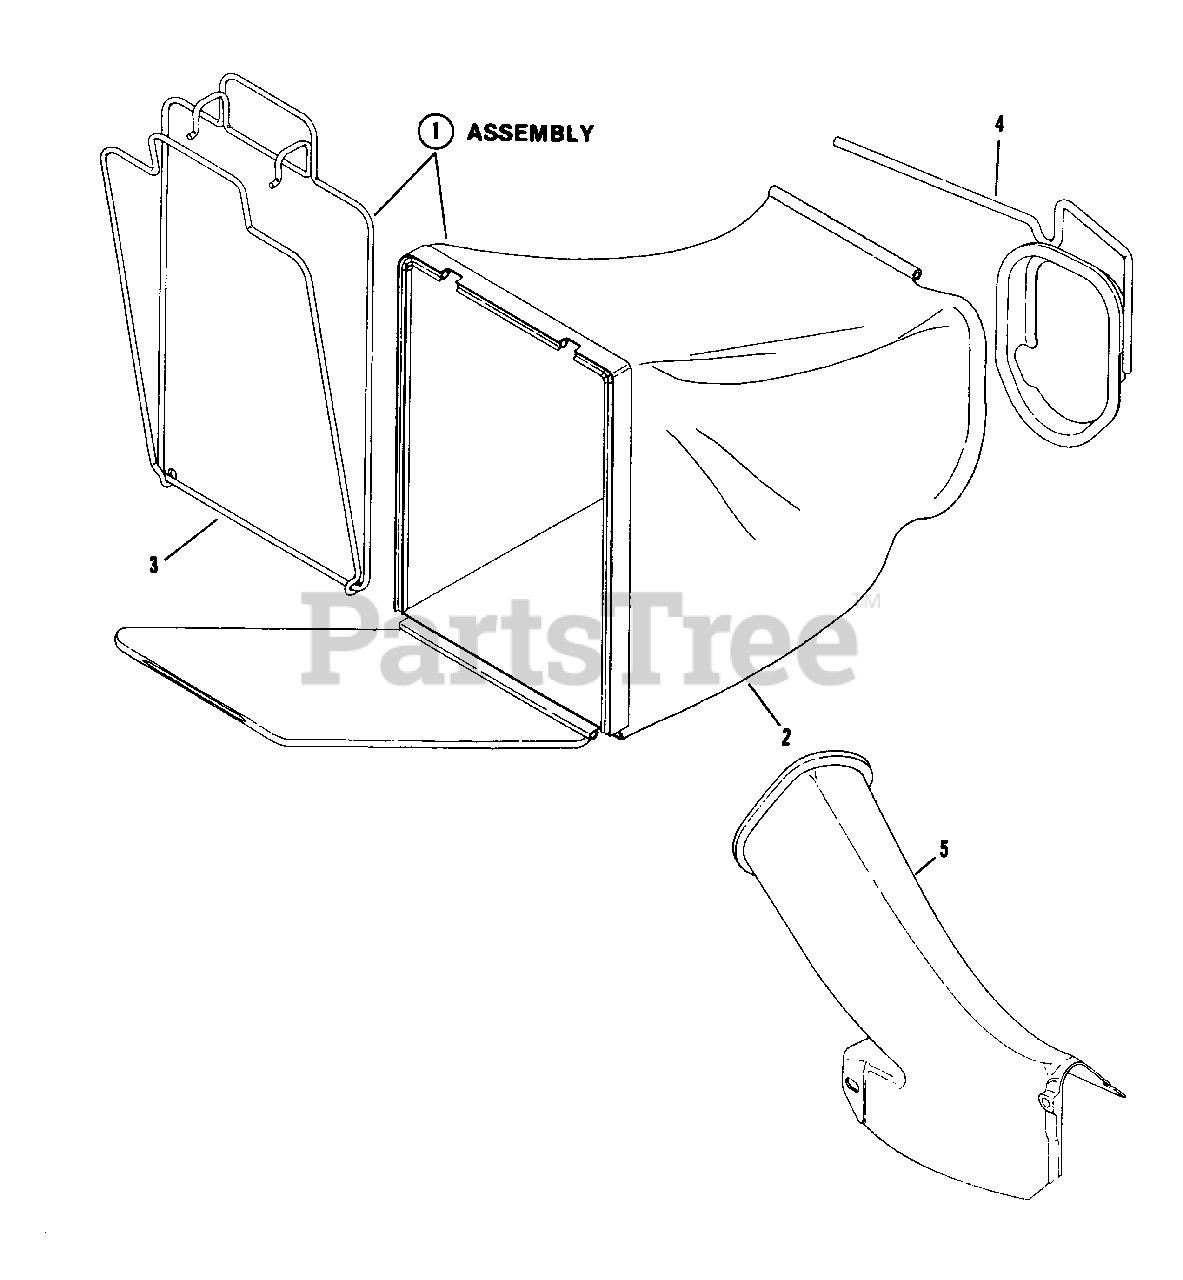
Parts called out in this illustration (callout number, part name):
1	ASSEMBLY, Grass Bag
2	BAG, KWIK-N-EZY
3	ASSEMBLY, Bag Wire
4	CONNECTOR, Grass Bag
5	ADAPTER, Bag
